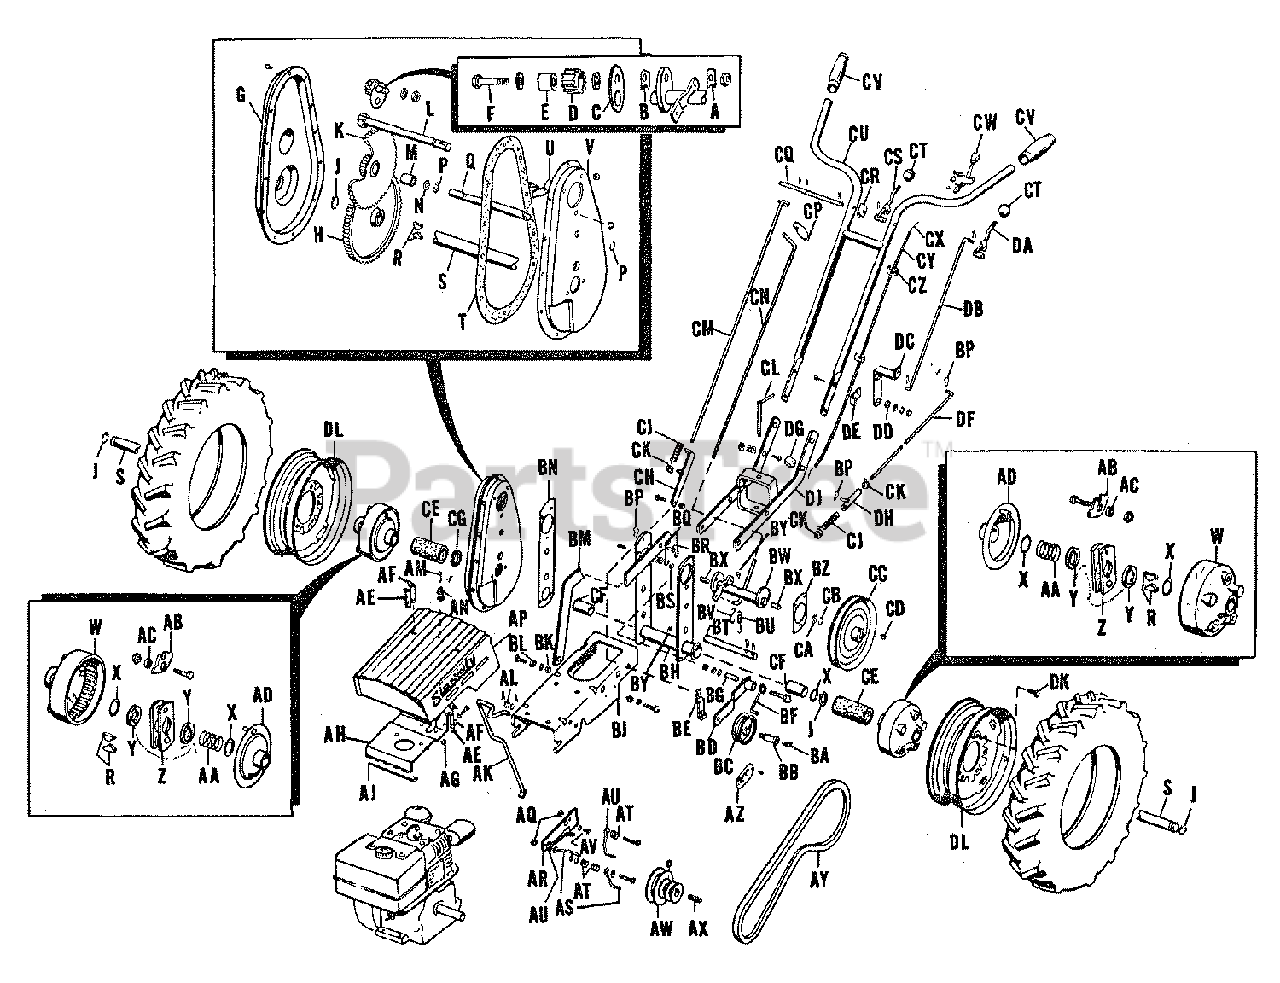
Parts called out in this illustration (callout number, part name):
A	LOCK PLATE
D	PINION, Reverse
G	COVER, Gear Case
H	GEAR, Drive
J	RING, Retaining
K	GEAR ASSEMBLY, Intermediate (Available Only As Two Gears, Assembled)
L	PINION AND PULLEY SHAFT ASSEMBLY
M	BEARING, Intermediate Pinion
P	RING, Retaining
Q	SHAFT, Intermediate
R	KEY, Hi-Pro, HP-608
T	GASKET, Gear Case
U	SPRING, Drag
V	CASE, Gear
W	HUB, Wheel
Y	WASHER, Axle
Z	CAGE ASSEMBLY, Ratchet
AA	SPRING, Axle
AD	COVER ASSEMBLY, Ratchet Cage
AE	LATCH, Stub
AF	LATCH, Stub
AG	NUT, Hex, Full, Lock, 1/4-20 NC
AH	BRACKET ASSEMBLY, Hood
AJ	PIN, Hinge
AK	STAND ASSEMBLY
AL	SPRING, Stand
AM	PIN, Hood
AN	SPRING, Hood
AP	HOOD ASSEMBLY
AQ	NUT, Hex, Jam, 5/16-18 NC
AR	HOLDER, Belt Stop
AS	STOP, Belt
AU	STOP, Belt
AV	SCREW, Holder
AW	PULLEY, Engine
AX	KEY, Engine Pulley
AZ	PLATE, Serial No.
BA	FITTING, Grease, Alemite #1911
BB	PIN, Idler Pulley
BC	PULLEY ASSEMBLY, Idler
BD	LEVER ASSEMBLY, Idler
BE	EXTENSION, Idler Lever
BF	STOP, Belt
BG	SPACER, Idler Lever
BH	HOUSING ASSEMBLY, Axle
BK	NUT, Hex, Full, Lock 3/8-16 NC
BL	SPACER, Lock Bar
BM	BAR, Lock
BN	GASKET, Bearing Housing
BP	CLIP, Spring
BS	NUT, Hex, Jam, 5/16-18 NC
BU	SPRING, Reverse Lever
BV	EXTENSION, Spring
BW	HOUSING ASSEMBLY, Bearing
BY	FITTING, Grease, Alemite #1641
CB	RING, Retaining
CC	PULLEY, Transmission
CD	KEY, Woodruff, #9
CE	TUBE, Rubber
CF	BEARING, Axle
CG	WASHER, Retainer
CH	CLUTCH ROD, Guide Assembly
CK	COLLAR, Set
CL	PIN ASSEMBLY, Hitch
CM	ROD, Clutch
CN	ROD, Reverse
CP	GRIP, Reverse Rod
CQ	SHAFT, Lever
CR	GUIDE, Reverse Rod
CS	LEVER ASSEMBLY, R.H.
CT	BALL, Clutch Lever
CU	HANDLE ASSEMBLY
CV	GRIP, Handle
CW	CONTROL, Throttle
CX	WIRE, Throttle
CY	CABLE, Throttle
CZ	CLIP, Throttle
DA	LEVER ASSEMBLY, L.H.
DB	ROD, Upper Idler
DC	LEVER, Lower Clutch
DE	STOP, Lever
DF	ROD, Lower Clutch
DG	CLAMP, Cable
DH	SOCKET ASSEMBLY, Rod
DJ	FRAME ASSEMBLY
